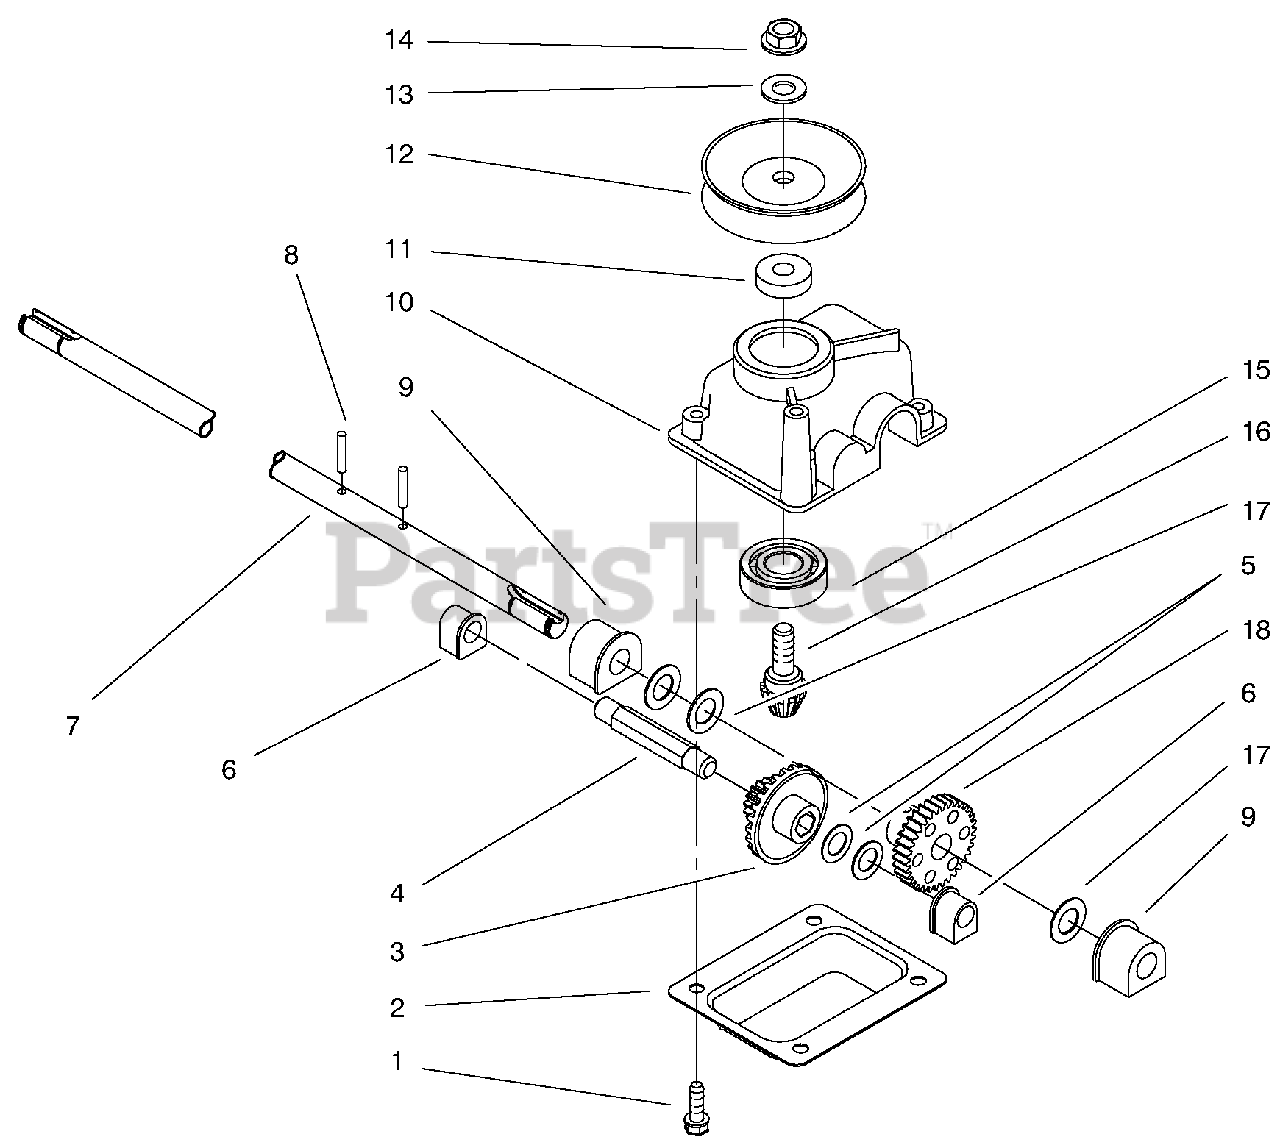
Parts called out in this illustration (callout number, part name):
1	Screw-Tapping
2	Cover-Gear Case
3	Pinion-15 Tooth
4	Shaft-Intermediate
7	Shaft-Output
8	Pin-Groove
9	Bushing-Output
10	Case-Gear
12	Pulley-Half
14	Nut-Lock
15	Bearing-Ball
16	Gear-Bevel Pinion
17	Washer-Thrust
18	Gear-34 Tooth
